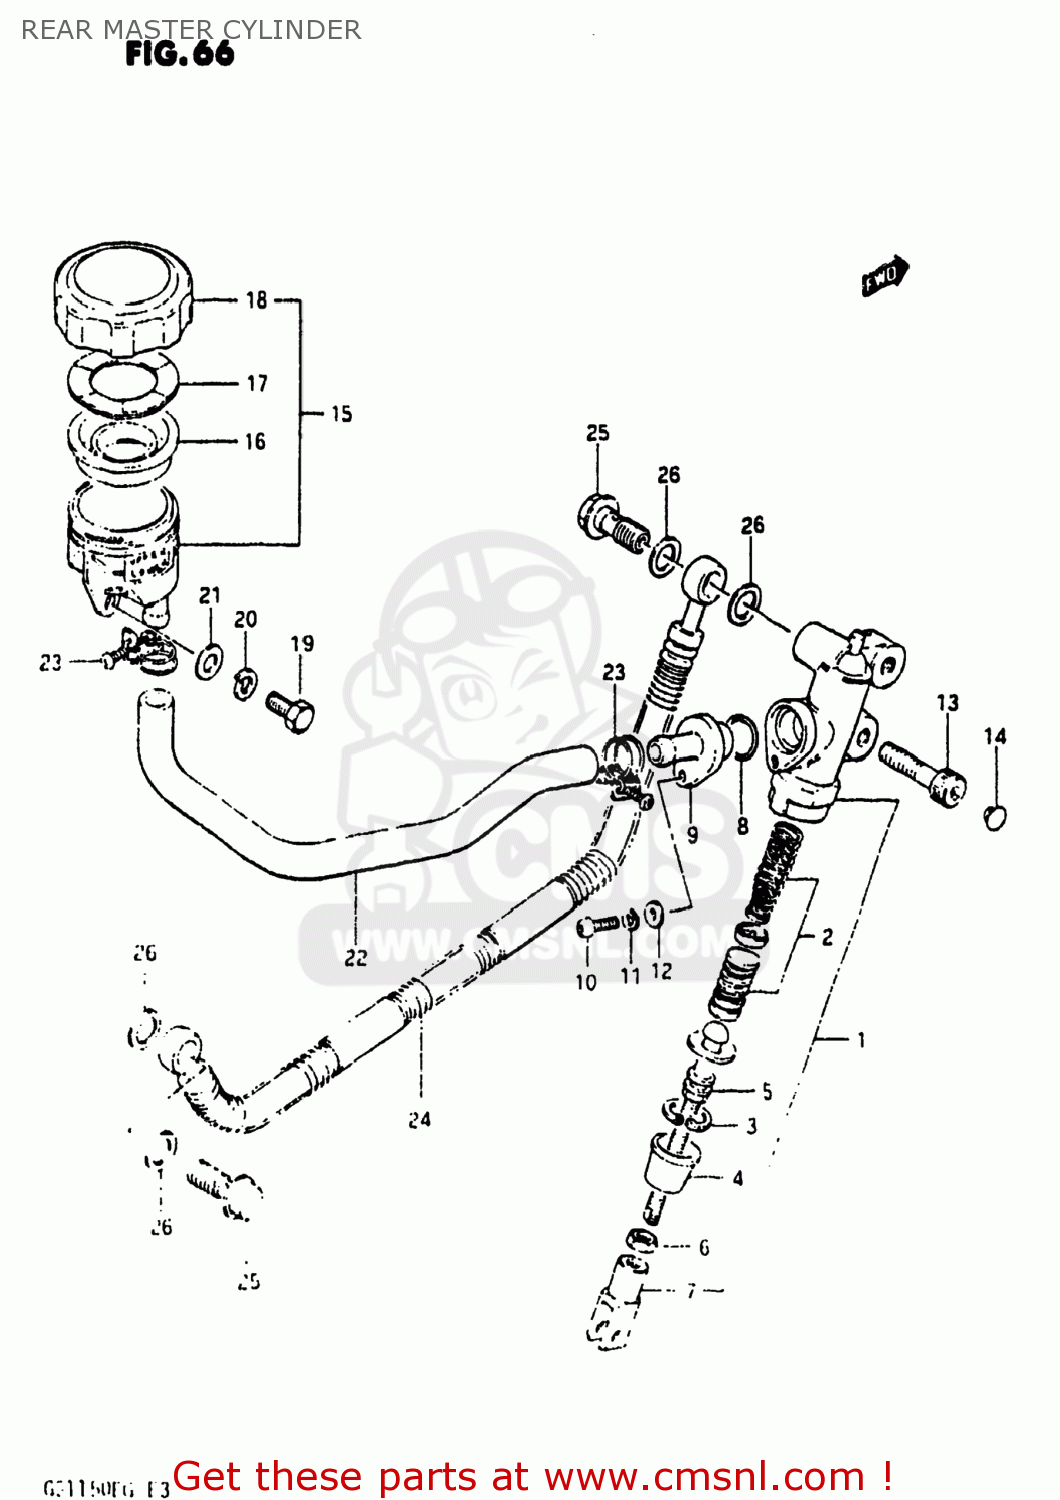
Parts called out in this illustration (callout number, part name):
1	CYLINDER ASSEMBLY,REAR MASTER
2	PISTON/CUP SET
3	CIRCLIP
4	BOOT
5	ROD,PUSH
6	NUT,MASTER CYLINDER
7	YOKE
8	O RING
9	CONNECTOR
10	SCREW
11	LOCK WASHER
12	WASHER
13	BOLT, FRONT RH
14	CAP(OD:10)
15	TANK ASSEMBLY,RESERVOIR
16	DIAPHRAGM
17	PLATE,DIAPHRAGM
18	CAP
19	BOLT 6X16
20	WASHER,LOCK
21	WASHER
22	HOSE,RESERVOIR TANK
23	CLAMP
24	HOSE,REAR BRAKE
25	BOLT UNION
26	WASHER(10X15X1.5)
